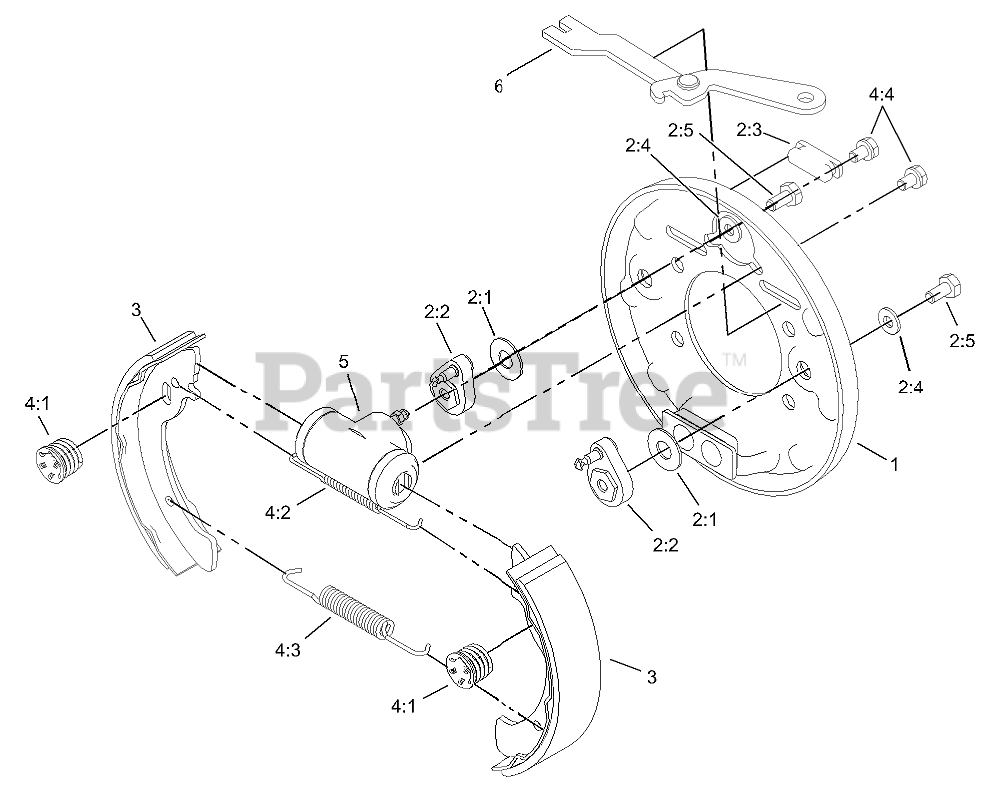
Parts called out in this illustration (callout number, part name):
1	BACKING PLATE ASM
2	ADJUSTER KIT
2:1	WASHER-BELLVILLE
2:2	ADJUSTER LEVER ASM
2:3	COVER-DUST
2:4	Washer
2:5	Bolt
3	SHOE AND LINING KIT
4	HARDWARE KIT
4:1	SHOE HOLD DOWN SPRING ASM
4:2	SPRING-UPPER
4:3	SPRING-LOWER
4:4	BOLT AND WASHER
5	WHEEL CYLINDER ASM
6	LH PARK BRAKE LEVER ASM
